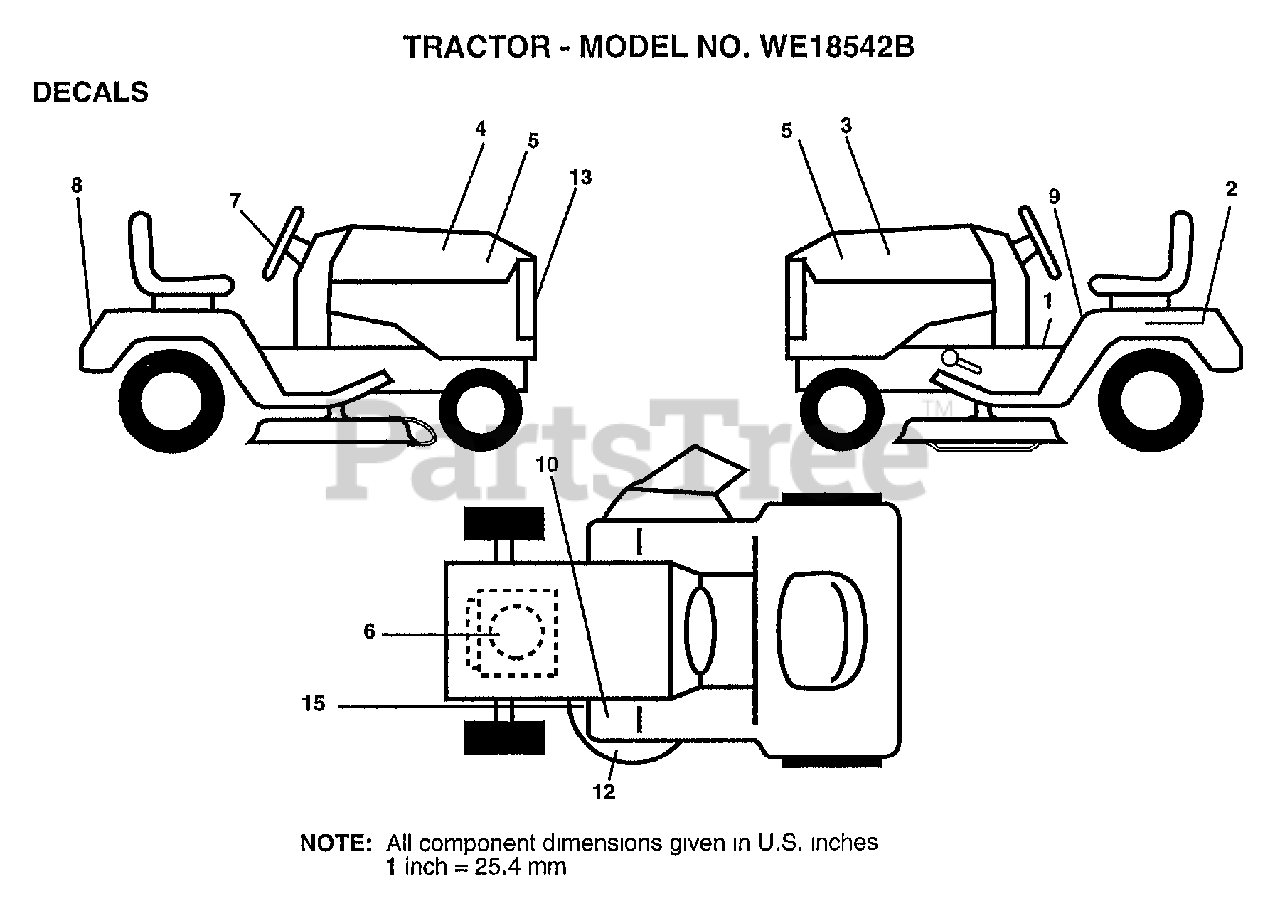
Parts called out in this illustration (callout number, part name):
1	"DECAL DASH,OPER."
2	DECAL.BATRY.3-3908
3	DECAL HOOD LH
4	"DECAL HOOD,RH"
5	"DECAL.PANEL,SIDE"
6	DECAL, HP, ENGINE
7	"DECAL INS,STRG WH"
8	DECAL-FENDER
9	"DECAL DANGER,FEND"
13	"DECAL GRILLE,LENS"
15	DECAL
